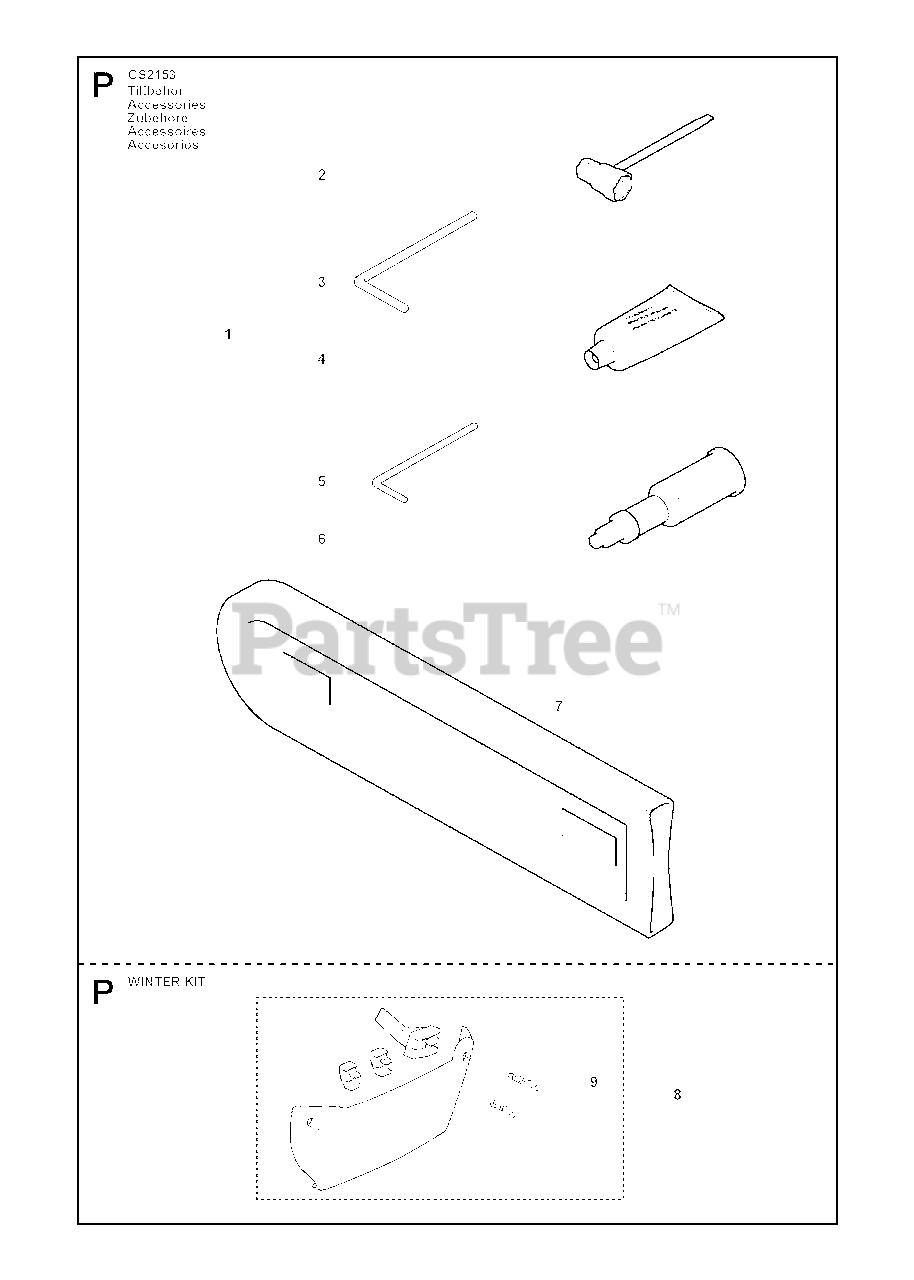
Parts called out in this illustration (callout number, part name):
1	TOOL KIT
2	COMBI TOOL
3	L-SPANNER
4	GREASE
5	L-SPANNER
6	GREASE GUN
7	BAR COVER
8	PROTECTOR
9	SCREW
